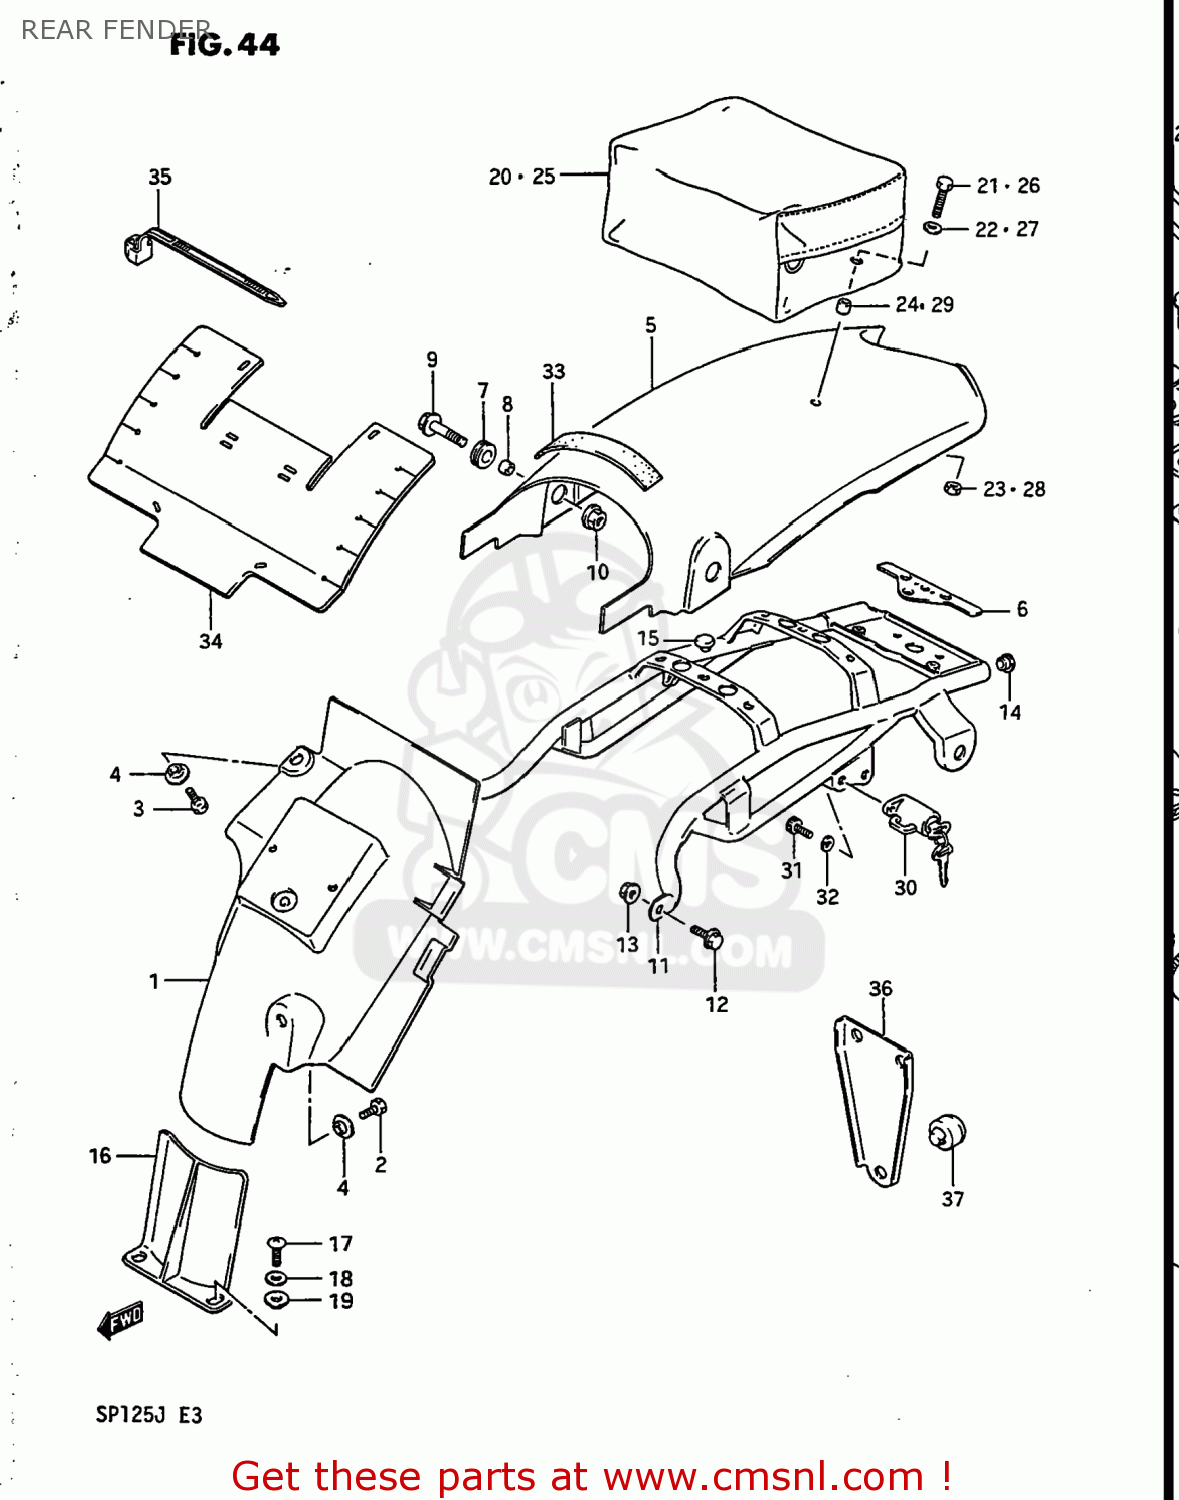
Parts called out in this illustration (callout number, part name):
1	FENDER,REAR
2	BOLT
3	BOLT 6X16
4	WASHER
5	FENDER,REAR
6	CUSHION,RR FENDER
7	CUSHION
8	SPACER (8.2X12X7.5)
9	BOLT
10	NUT
11	REINFORCEMENT,REAR FENDER
12	BOLT
13	NUT
14	PLUG
15	CUSHION
16	GUARD,RR UNIT MUD
17	SCREW
18	WASHER(6.5X16X1.2)
19	WASHER,LOCK
20	BAG SET,SEAT TAIL
21	BOLT
22	WASHER
23	NUT
24	SPACER (6.1X9X9)
25	BAG ASSEMBLY,SEAT TAIL
26	BOLT
27	WASHER
28	NUT
29	SPACER (6.1X9X9)
30	LOCK ASSEMBLY,HELMET
31	BOLT 6X11
32	WASHER,LOCK
33	CUSHION(25X185X15)
34	FLAP,AIR CLEANER MUD
35	CLAMP(L:125)
36	HOLDER,LICENSE PLATE CUSHION
37	CUSHION
